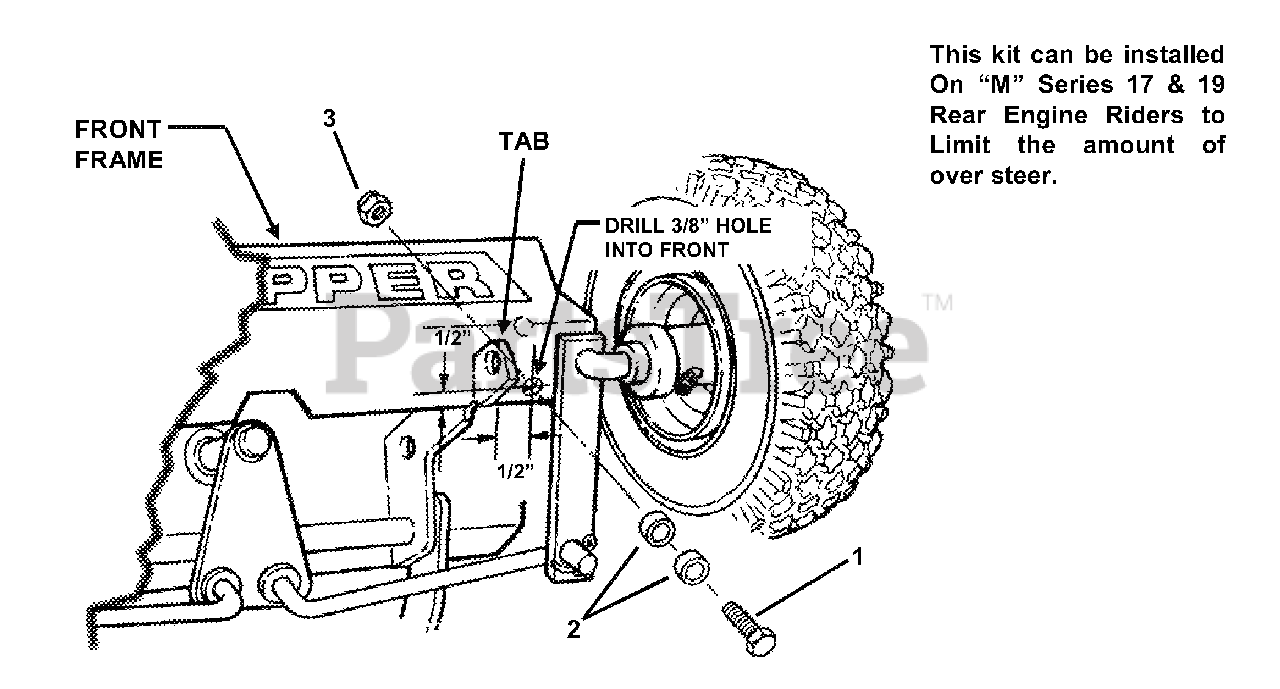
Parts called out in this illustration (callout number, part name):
1	SCREW, 3/8-16 x 1" Hex Head Cap, Grade 5
2	SPACER
3	NUT, 3/8-16 Hex Center Lock
